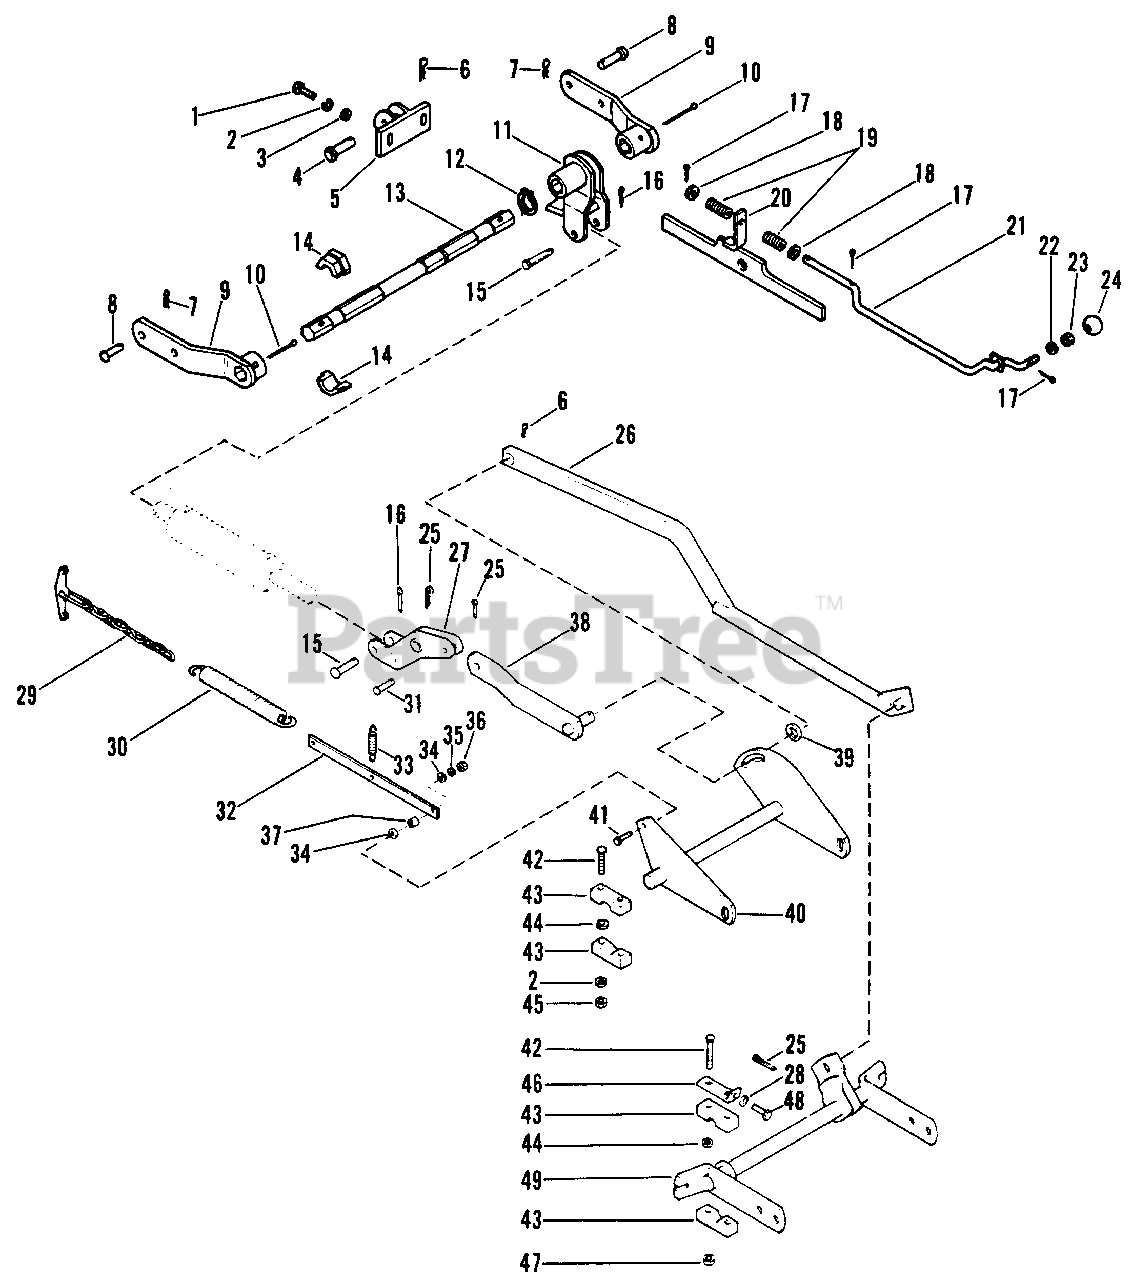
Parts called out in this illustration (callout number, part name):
1	Bolt, Hex 3/8-16 x 1.00
2	Washer, Lock 3/8 Reg.
3	Washer, Flat .438 x 1.000 x .083
4	Clevis Pin
5	Plate
6	Hairpin, Internal
7	Pin, Hair
8	Rivet, Button .50 x 1.25
9	Arm
10	Pin, Cotter .187 x 2.00
11	Arm
12	Snap Ring, Ext. 1.125 Sft. x .050
13	Shaft
14	Bushing, Flange
15	Clevis Pin
16	Pin, Cotter .125 x 1.00
17	Pin, Cotter .125 x .75
18	Washer, Flat .406 x .812 x .065
19	Spring, Comp. 1.50 Free Length
20	Latch
21	Latch Rod
22	Washer, .401/.411 x 1.00 x .062
23	Nut, Jam 3/8-16 Hex
24	Knob, Steering Lock
25	Pin, Cotter .187 x 1.25
26	Connector Link
27	Bellcrank
28	Washer, Lock 5/16 SP
29	Chain
30	Spring, Ext. 8.672 Free Length
31	Rivet, Button .625 x 1.50
32	Link
33	Spring, Ext. 2-3/4 Free Length
34	Washer, Flat .281 x .625 x .065
35	Washer, Lock 1/4 Reg.
36	Nut, Hex 1/4-20
37	Spacer
38	Link
39	Washer, Flat .812 x 1.496 x .134
40	Center Rockshaft
41	Bolt, Hex 1/4-20 x 1.00
42	Bolt, 3/8-16 x 2.25 Rd Hd Sq Nk
43	Block
44	Washer, .397/.407 x .750 x .005
45	Nut, Hex 3/8-16
46	Brace
47	Nut, Lock 3/8-16
48	Bolt, Hex 5/16-18 x 1.25
49	Rockshaft, Front
NS	Fitting, Lube 1/4-28
